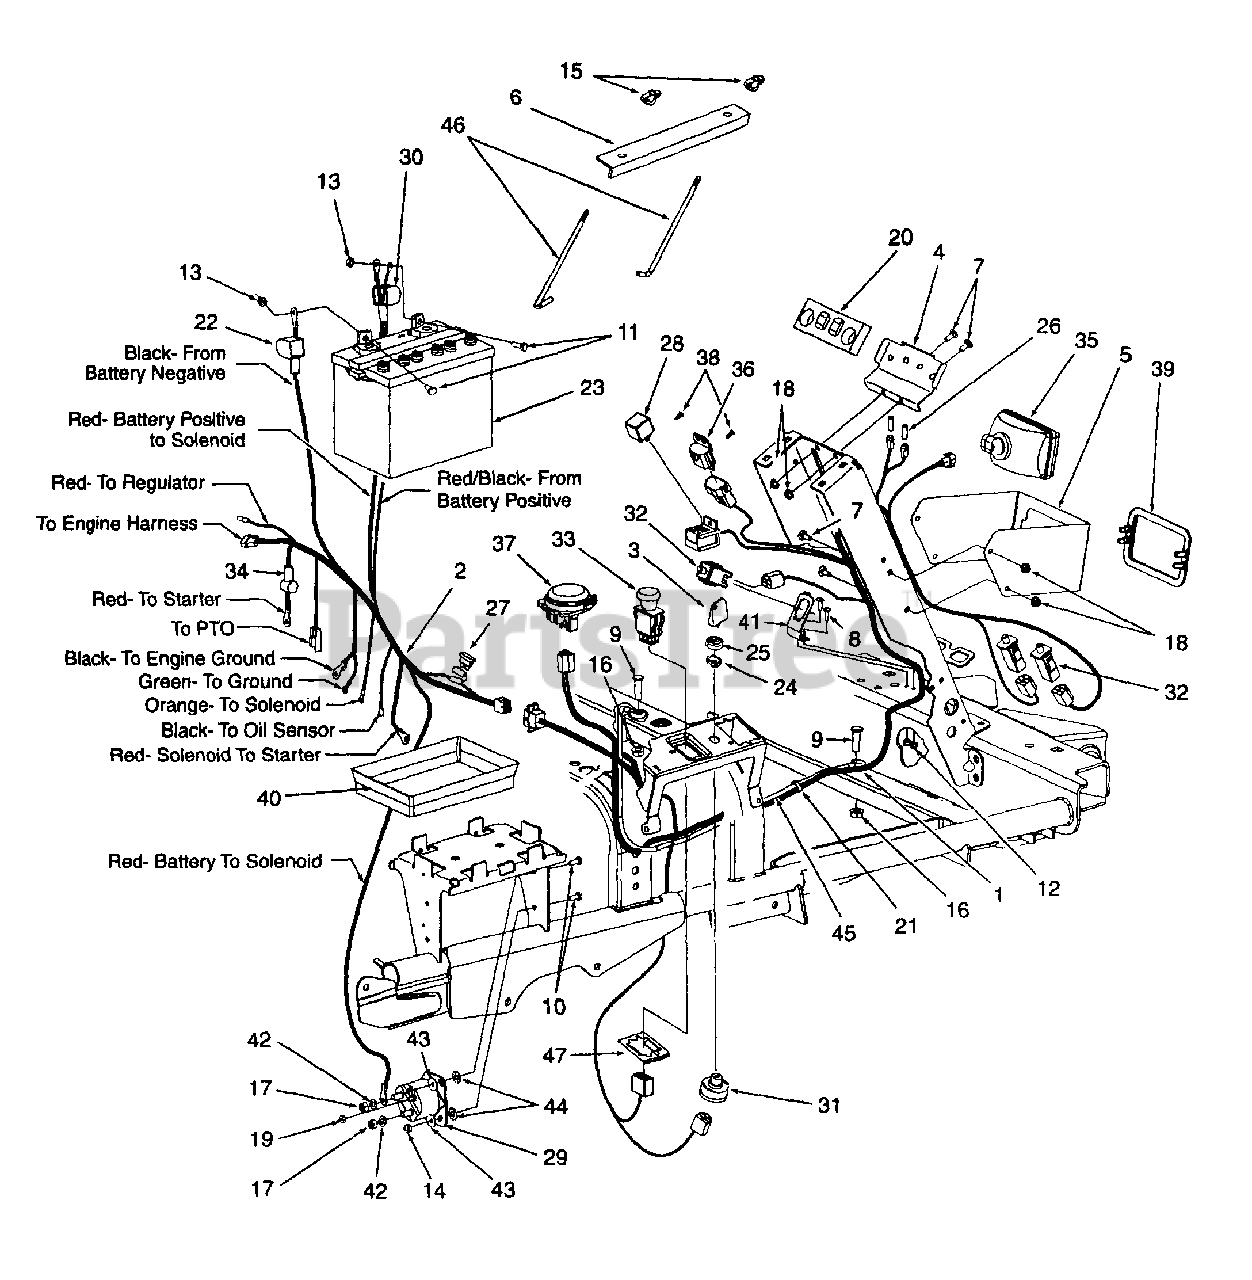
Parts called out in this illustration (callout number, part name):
1	Wire Harness, Main
2	Wire Harness, Engine
3	Key, Ignition
7	Bolt, Carriage, 1/4-20 x .62
8	Screw, Machine, #10-24 x 5/8
9	Screw, Hex Cap, 3.8-16 x 1.25
10	Screw, Hex Cap, 1/4-20 x .62 GR5
11	Screw, Hex Cap, 1/4-20 x .75 GR5
12	Nut, Hex Insert Lock, #10-24
13	Nut, Hex Sems, 1/4-20
14	Nut, Hex Center Lock, 1/4-20
15	Nut, Nylon Wing, 1/4-20
16	Nut, Hex Flange Lock, 3/8-16
17	Nut, Hex, 5/16-18
18	Nut, Hex Flange Lock, 1/4-20
19	Nut, Hex Sems, #10-32
20	Foam Protector, Indicator Light
22	Cover, Battery Terminal - Black
23	Battery
24	Nut, Ignition Switch, 5/8-32
25	Cap, Ignition Switch
26	Bulb,Indicator
27	Fuse, Mini, 20Amp
28	Relay
29	Solenoid Switch
30	Cover, Battery Terminal - Red
31	Switch, Ignition
32	Switch, Plunger Safety
33	Switch, PTO
34	Cover, Terminal - Red
35	Headlight Assembly
36	Sensor, Voltage
37	Switch, Seat
38	Retainer, Ratcheet
39	Bezel, Headlight
40	Tray, Battery
41	Spring, Switch Mounting
42	Washer, Lock, 5/16
43	Washer, Bell, .265 x .75 x .062
44	Washer, Int./Ext. Lock, 1/4 ID
45	Rod, Harness Mtg
46	Rod, Battery Retainer
47	Bracket, PTO Switch Retainer
